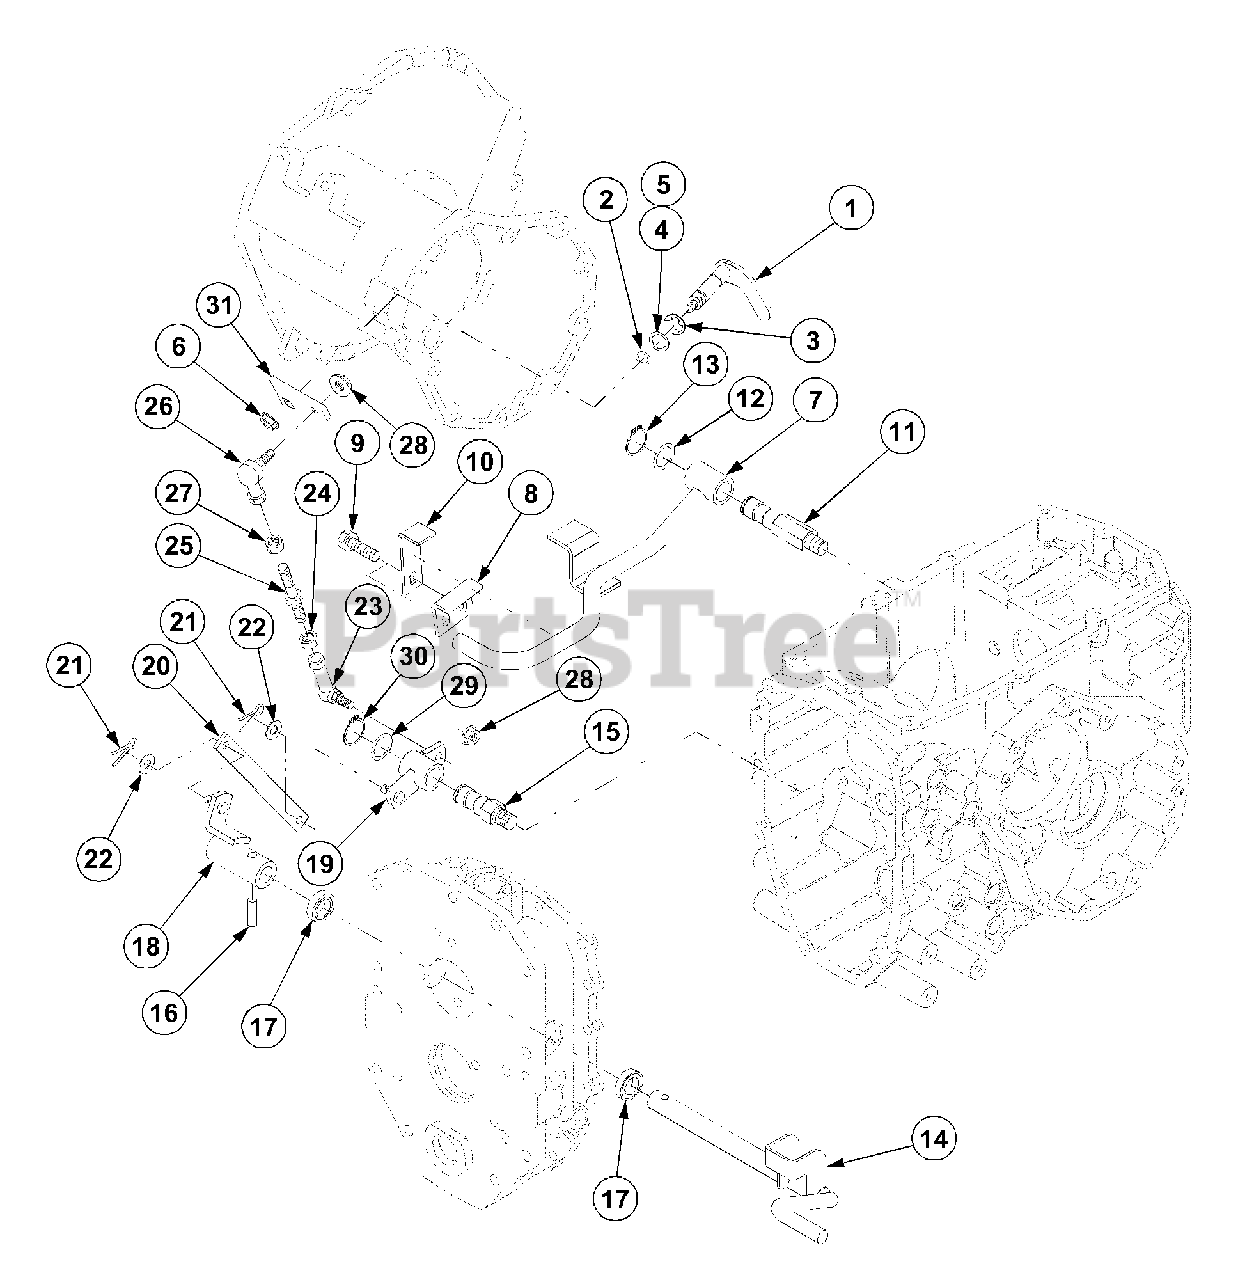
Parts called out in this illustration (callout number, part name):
3	E-Ring
7	Pedal,Diff Lock
8	Plate
9	Bolt,w/Washer
10	Plate
11	Shaft
12	Liner
13	C-Ring
14	Pedal,Difflock
21	Pin,Split
31	Arm,Diff Lock
